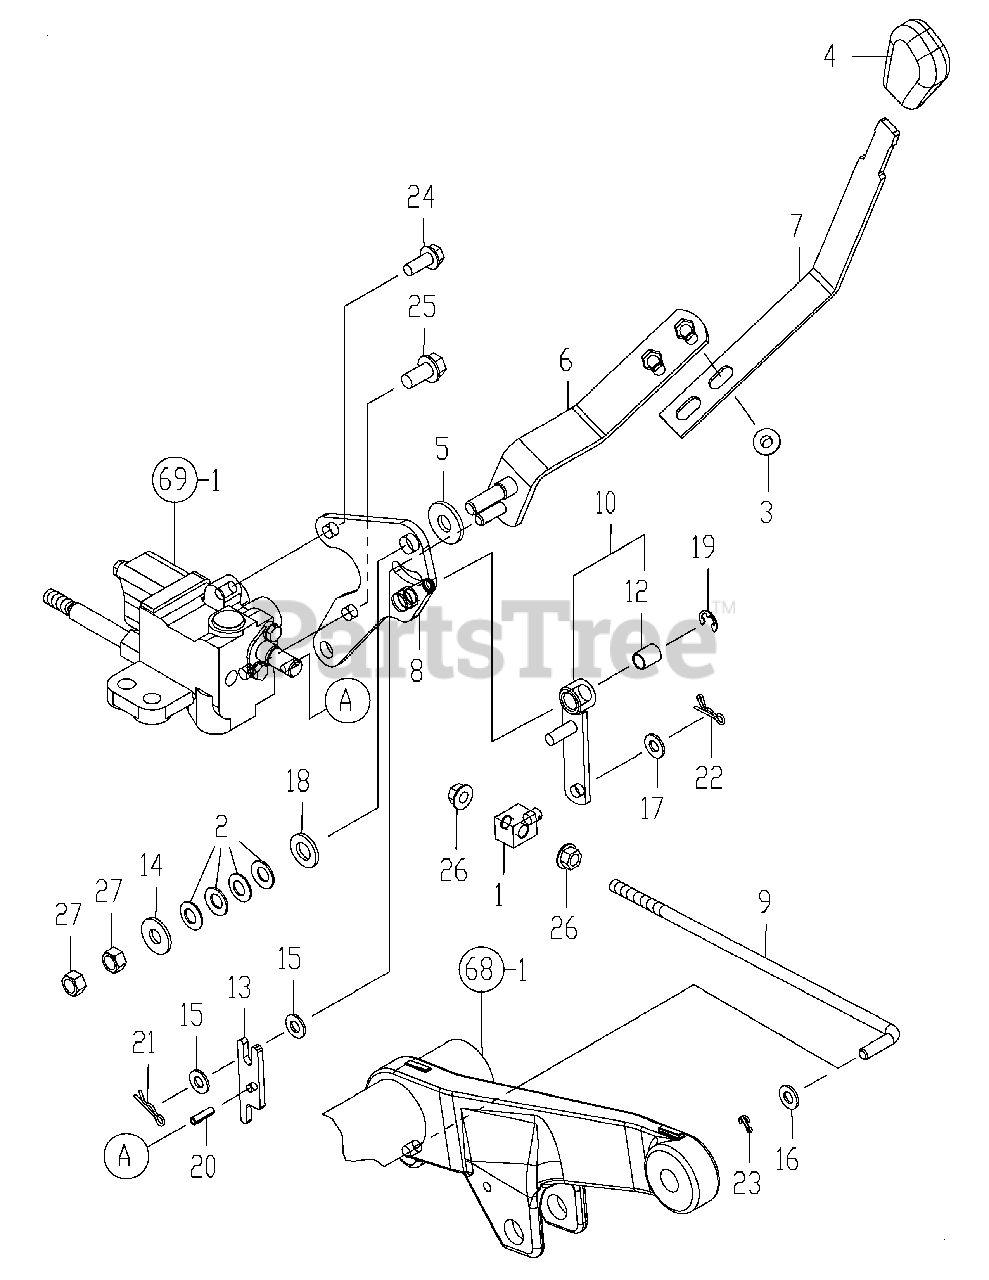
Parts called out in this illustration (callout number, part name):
2	WASHER, CONICAL 10
5	PLATE, FRICTION
6	LEVER CMP, POSITION
7	LEVER,POSITION
8	STAY CMP, HYD. LINK
10	LEVER ASY, CONTROL
12	BEARING, 10 X 15
20	PIN, 5.0A X 18
